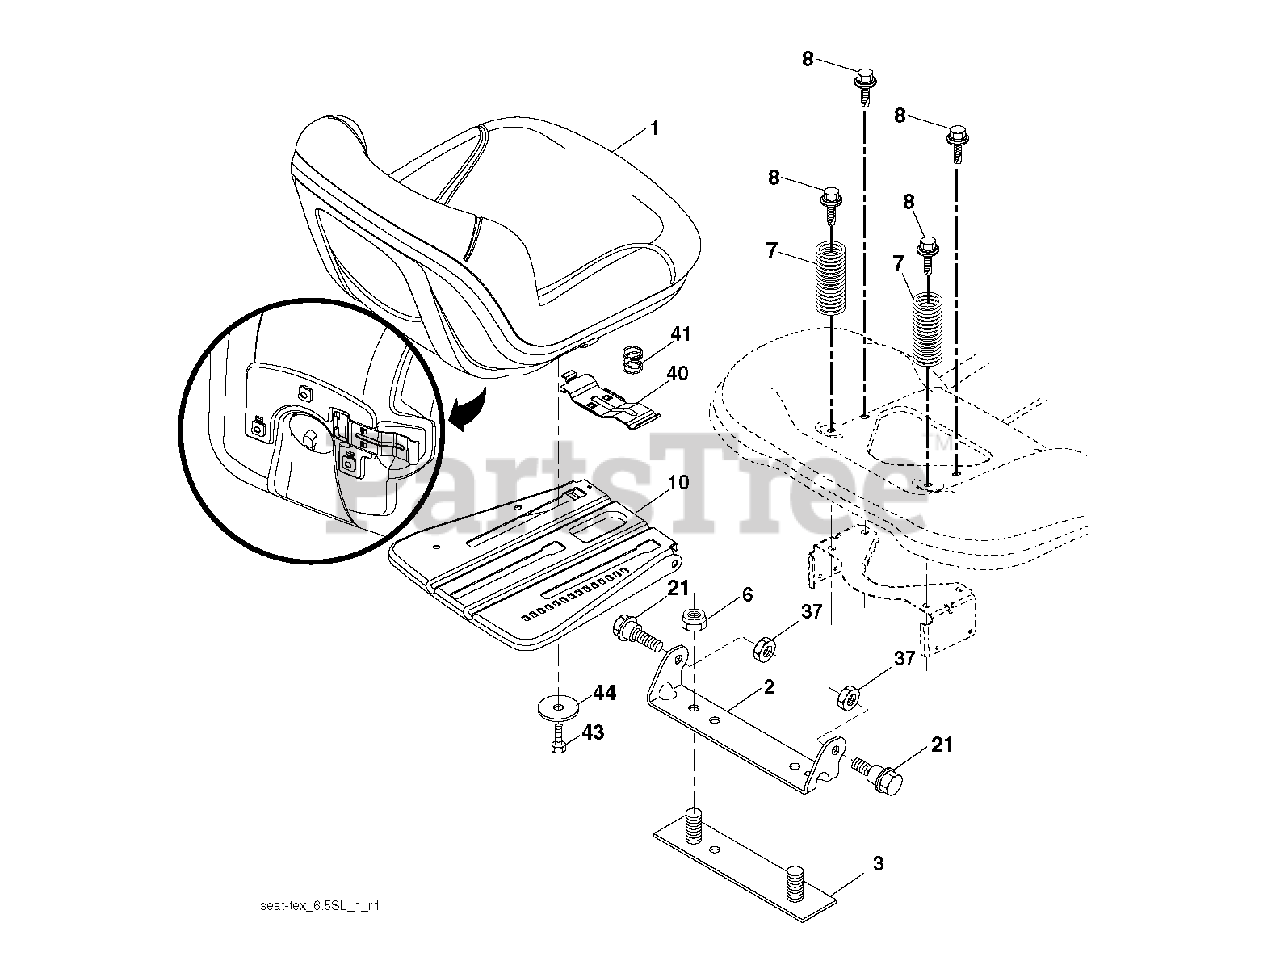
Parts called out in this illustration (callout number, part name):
1	SEAT.TH150.MS498.GRY.HUSQ.TEX
2	BRKT.PIVOT.FENDER
3	STRAP
6	NUT
7	SPRING COMPRESSION
8	BOLT, 5/16-18 X 1 3/4
10	PAN.ASM.SEAT.3PT
21	BOLT.SHOULDER.5/16-18
37	NUT.71038.31-18.HEX.NYLOCK
40	HANDLE.SLIDE.SEAT.TEX.BLACK
41	SPRING.LATCH.SEAT.TEX
44	WASHER 13/32 X 2-3/8 X 12GA
